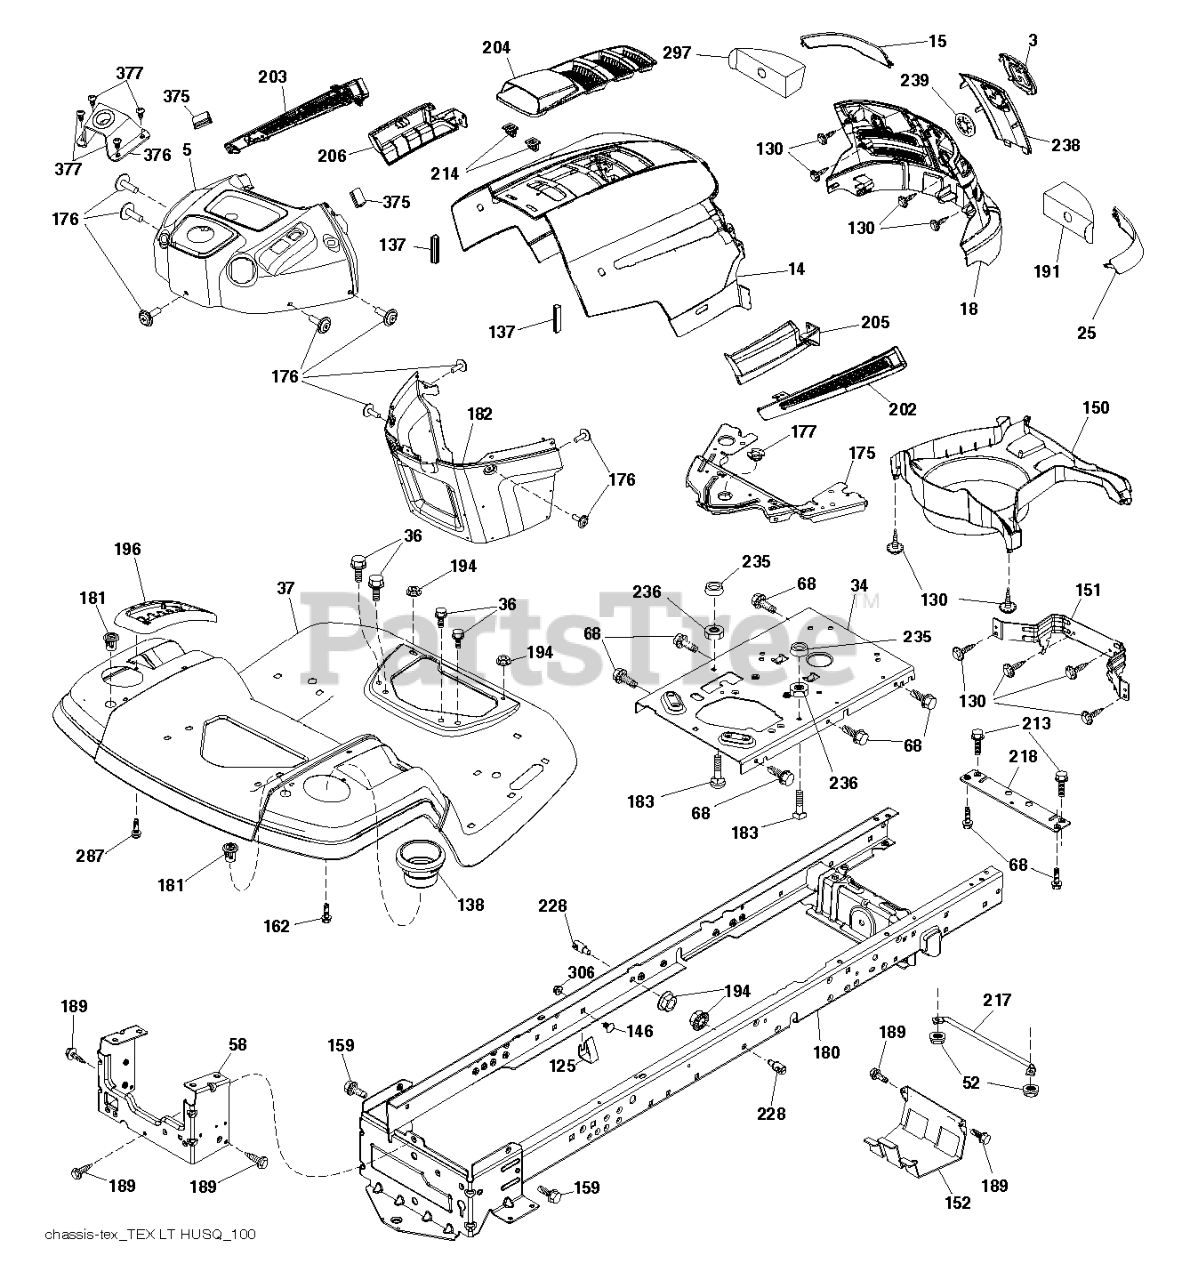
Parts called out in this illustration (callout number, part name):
3	LOGO.HUSQ.GT.LT.CROWN.H
5	SUBASM.DASH.UPPER.HLT.498
14	HOOD.HUSQVARNA.LT.ORANGE
15	LENS.HUSQVARNA LT.RH
18	GRILLE.SVC.HUSQVARNA.GREY
25	LENS.HUSQVARNA LT.RH
34	PLATE.ENGINE.WELDED.CHASSIS
36	SCREW 5/16"
37	FENDER.TLT.PDL.CNTRL.W/CPH.ORG
58	DRAWBAR UPPER 2PC SMALL FENDER
125	CLIP.FUEL.LINE
137	BUMPER DASH
138	HOLDER.CUP.LT.GREY
146	BOLT.RDHD.SHT.SQNK.3/8-16X5/8
151	BRACKET PIVOT
152	SHIELD.BROWNING.W/TEX
159	SCREW, 3/8-16X3/4
175	CROSSMEMBER
176	SCREW.#10-24X5/8.RN.QU
177	BUSHING STEERING
180	CHASS.WLDMNT.TL.12GA/2P.48/54
181	BUSHING.MNT.FEND.CRGO.TEX.49
182	DASH.LOWER.PREDATOR LT
189	SCREW
191	INSERT.REFLECTIVE.RH.
196	DECKLFT.CONSOL FULL ASSM GREY
202	VENT.SIDE.HUSQVARNA.LT.RT
203	VENT.SIDE.HUSQVARNA.LT.LFT
204	SUBASM.TOP.VENT.HUSQ.LT
205	SKIRT.SIDE.HUSQVARNA.LT.RT
206	SKIRT.SIDE.HUSQVARNA.LT.LEFT
213	SCREW HEXAGON HEAD SCREW 5/16-
214	CLIP.RETAINER.TINNER.
217	ROD.PIVOT.HOOD
218	X-PIECE.HOOD.STOP.NON/
228	STUD.W/"D"ANTI-ROTATION
236	NUT.CENTERLOCK.5/16-
238	TRIM.HUSQ LT.668
287	SCREW 1/4X20
297	INSERT REFLECTIVE
306	NUT LOCK FLG 3/8-16 UNC
375	BUMPER CLIP-ON. DASH 1"
376	MOUNT.ASM.HUSLT.UPPER.STRNG
377	SCREW 10 X 1/2 ZN PL PHIL PAN
